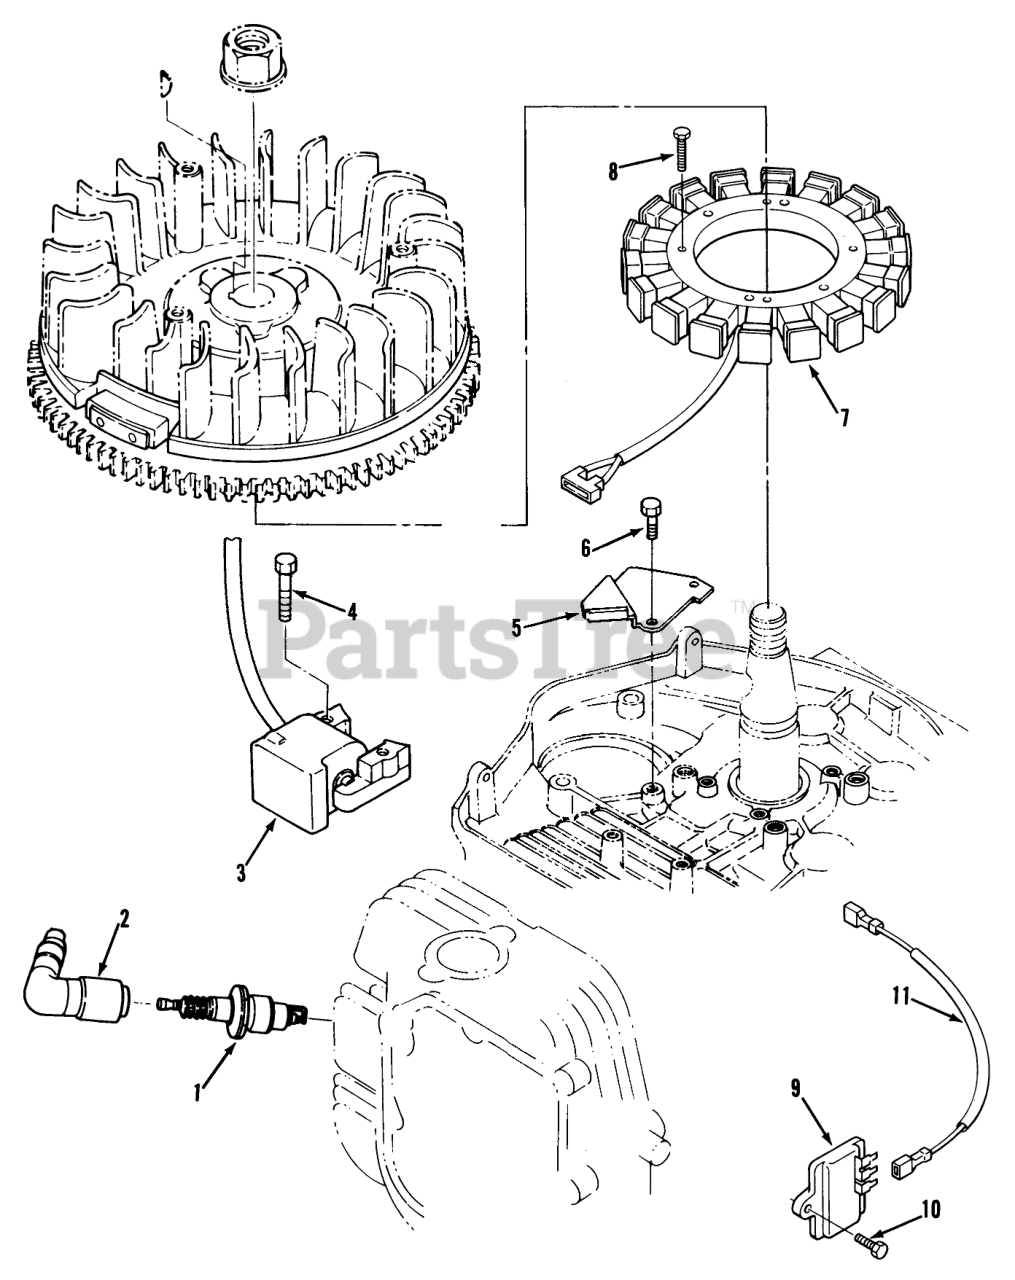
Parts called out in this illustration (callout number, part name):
1	Plug-Spark
3	COIL-IGNITION
4	HHSTB-M6 X 27MM
5	CLAMP-CORD
6	HHSTB-M6 X 14MM
7	STATOR
8	SCREW
9	Regulator
10	HHSTB-M6 X 14MM
11	HARNESS
